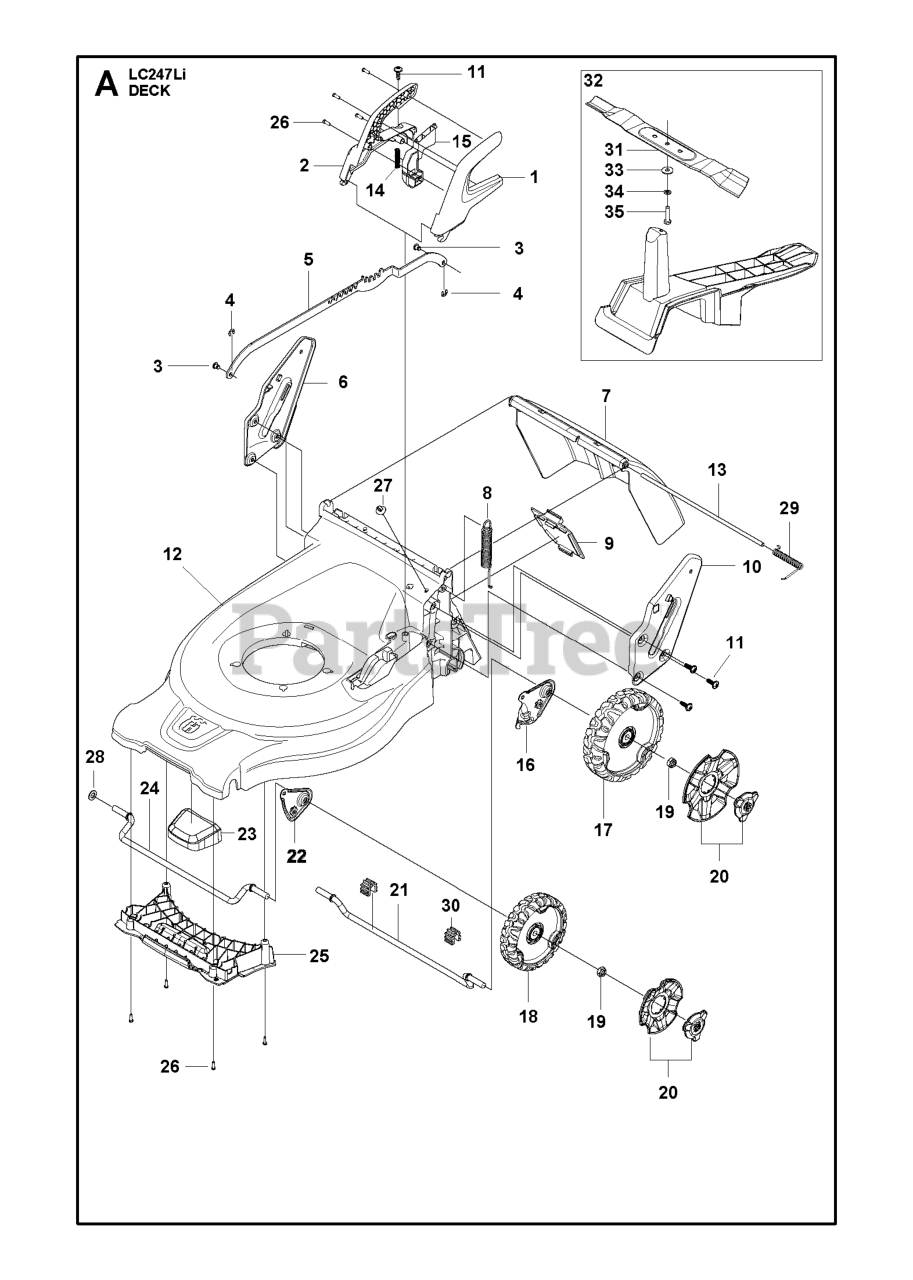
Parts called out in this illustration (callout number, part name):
4	Retaining Ring
20	HUB CAP
26	SCREW ITXPANT T50X16 ZN/FE (A
28	Washers
34	SPRING WASHER
35	SCREW
